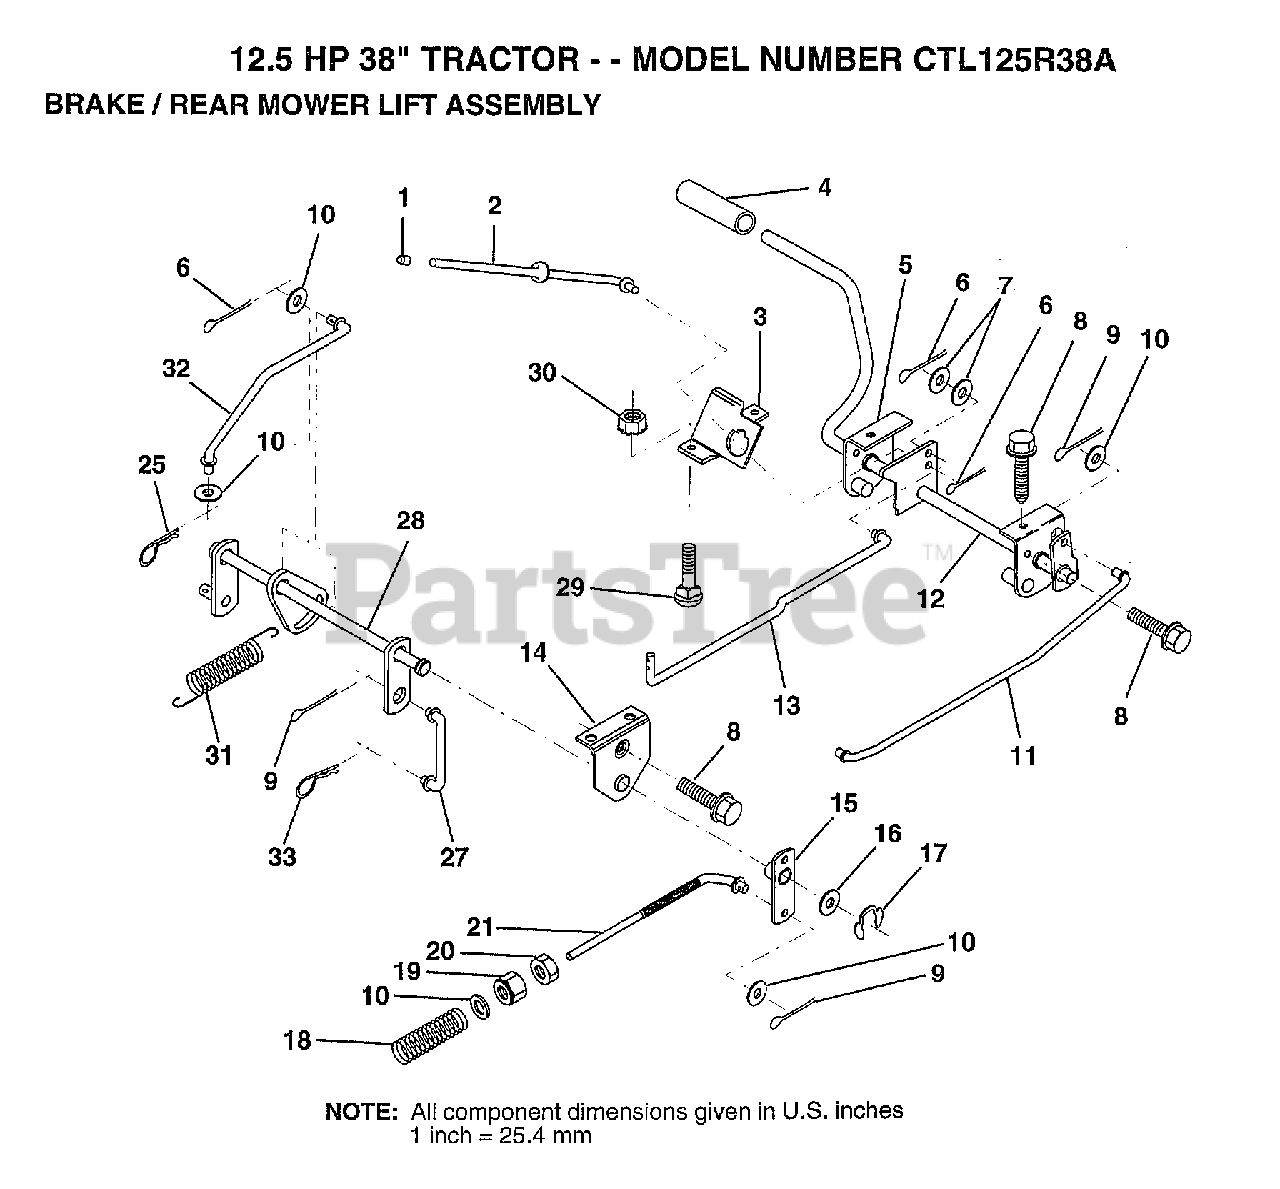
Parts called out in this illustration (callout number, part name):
2	"ROD,PARK BRAKE"
3	"BRKT,PARK BRAKE"
4	PEDAL COVER T
5	BRK ASM CLUT LH
7	WASHER
8	SCREW LT
9	COTTER PIN
10	WASHER
11	"ROD,FRT BRAKE"
12	ASM CLUTCH/BRK PD
13	"ROD,CLUTCH"
14	"BRKT,LIFT SHAFT"
15	BRAKE PIVOT ARM
16	WASHER T
17	KLIP RING
18	SPRING ROD LT
19	NUT
25	SPRING.RETAINER
27	LINK LIFT REAR LR
28	LIFT ASM MWR RE
31	COUNTER SPRING
32	LINK LIFT LEVER
